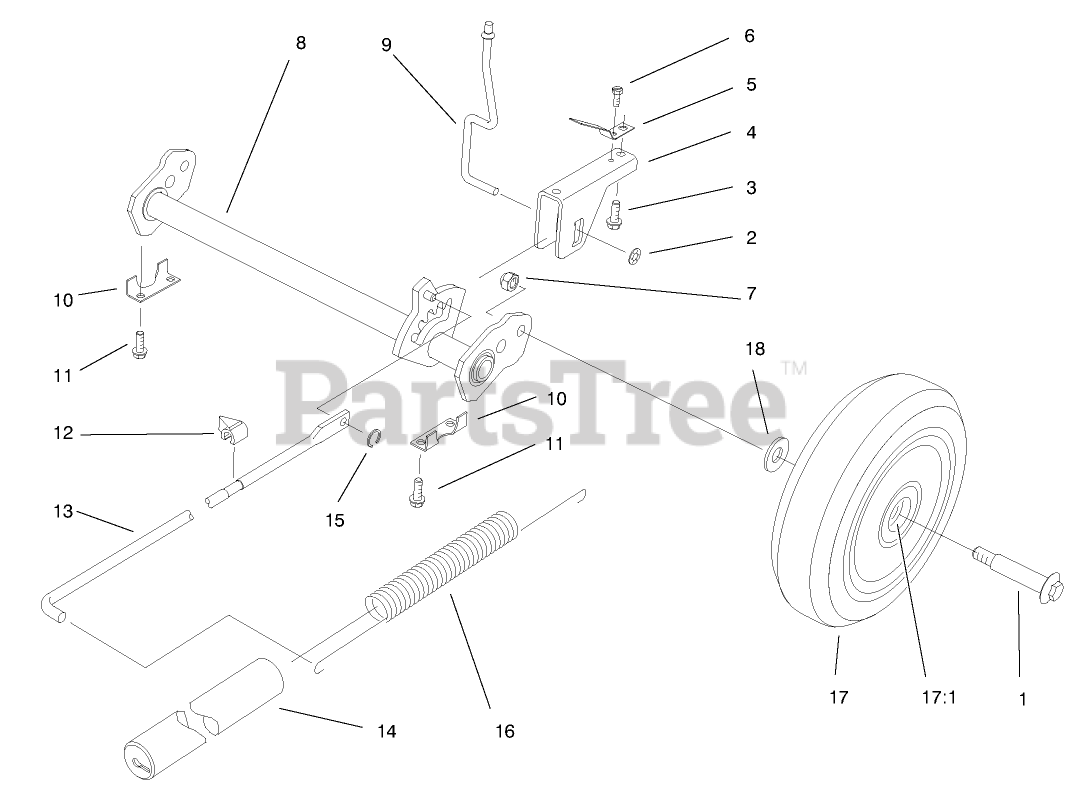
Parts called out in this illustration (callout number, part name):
1	BOLT-WHEEL
2	PUSHNUT
3	SCREW
4	SADDLE - HOC
6	SCREW 8 - 32 X 250
7	NUT-HEX
8	PIVOT ARM REAR WA
9	TRIGGER ROD
11	SCREW-HWH
12	INDICATOR-HEIGHT OF CUT
13	LINK ROD
14	COVER-SPRING
15	GRIP RING
16	SPRING-COUNTERBALANCE
17:1	BUSHING
18	WASHER
